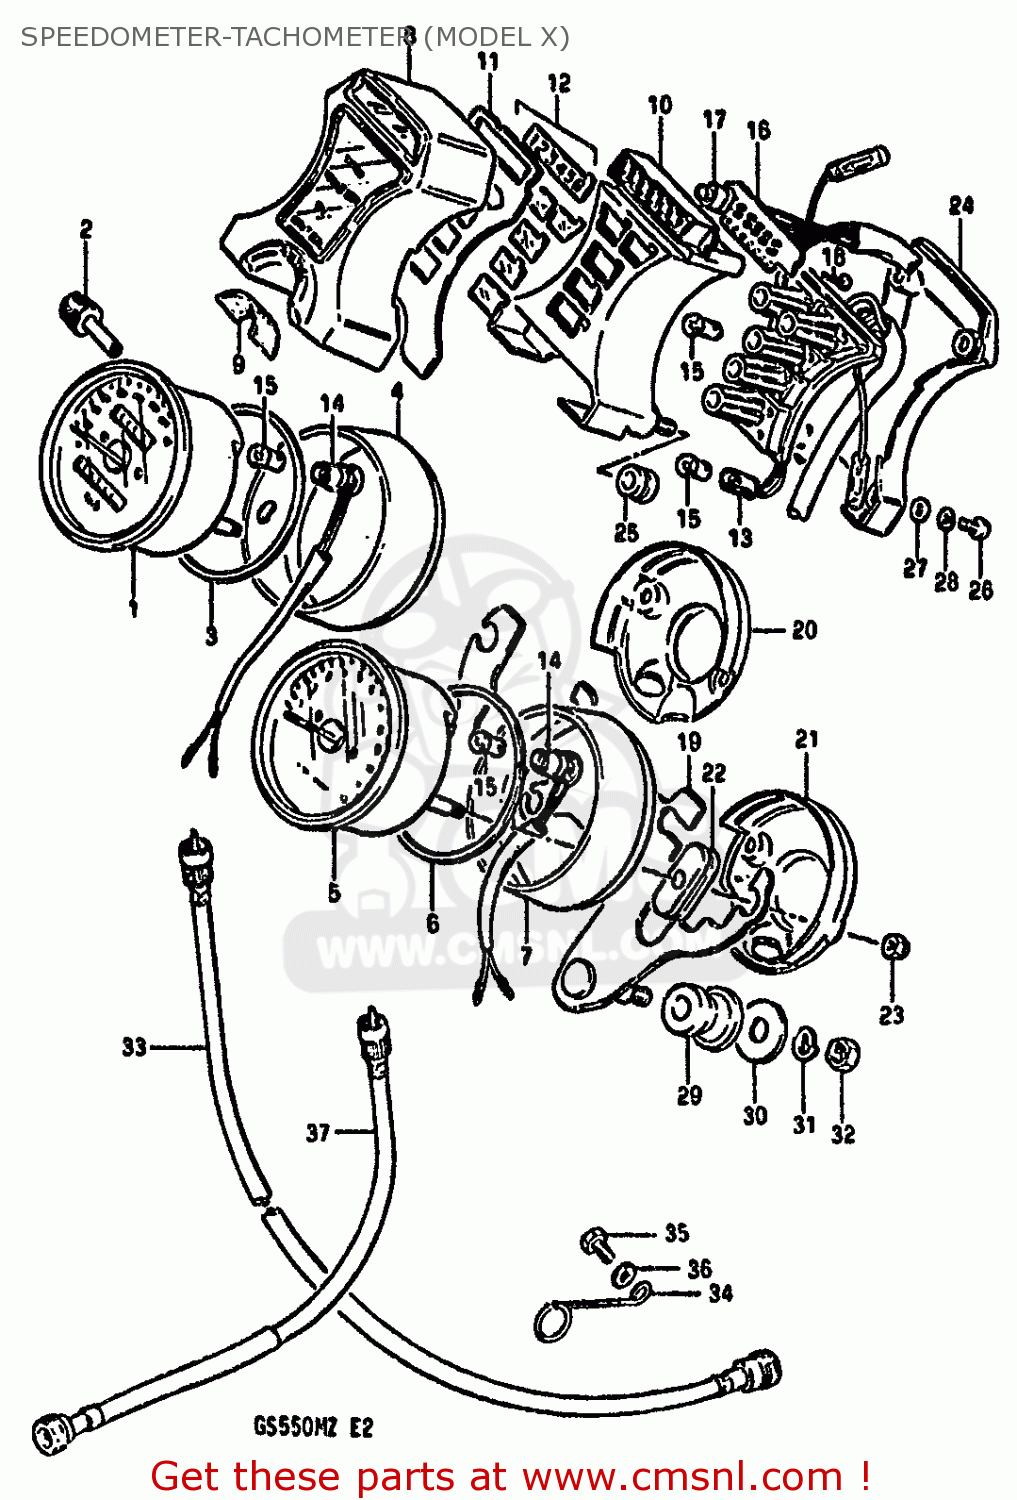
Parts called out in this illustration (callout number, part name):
1	SPEEDOMETER
2	KNOB,TRIP
3	CUSHION,SPEEDOMETER
4	COVER,SPEEDOMETER
5	TACHOMETER
6	CUSHION,SPEEDOMETER
7	COVER,TACHOMETER
8	CASE,PILOT BULB
9	PAD
10	CASE,PILOT BULB,INNER
11	PLATE,PILOT BOX
12	LENS SET,PILOT LAMP
13	SOCKET
14	SOCKET,METER
15	BULB(12V3.4W,STANLEY,A72A)
16	SOCKET,GEAR INDICATOR
17	BULB(14V1.12W)
18	SCREW,GEAR INDICATOR
19	BRACKET,COMBINATION METER
20	COVER,SPEEDOMETER,UNDER
21	COVER,TACHOMETER,UNDER
22	CUSHION,METER
23	NUT
24	COVER,PILOT BOX,UNDER
25	CUSHION
26	SCREW
27	WASHER
28	LOCK WASHER
29	CUSHION,METER BRACKET
30	WASHER (8.5X29X1.6)
31	LOCK WASHER
32	NUT
33	CABLE ASSEMBLY,SPEEDOMETER
34	CLAMP,SPEEDOMETER CABLE
35	BOLT, UPPER
36	WASHER
37	CABLE ASSEMBLY,TACHOMETER
